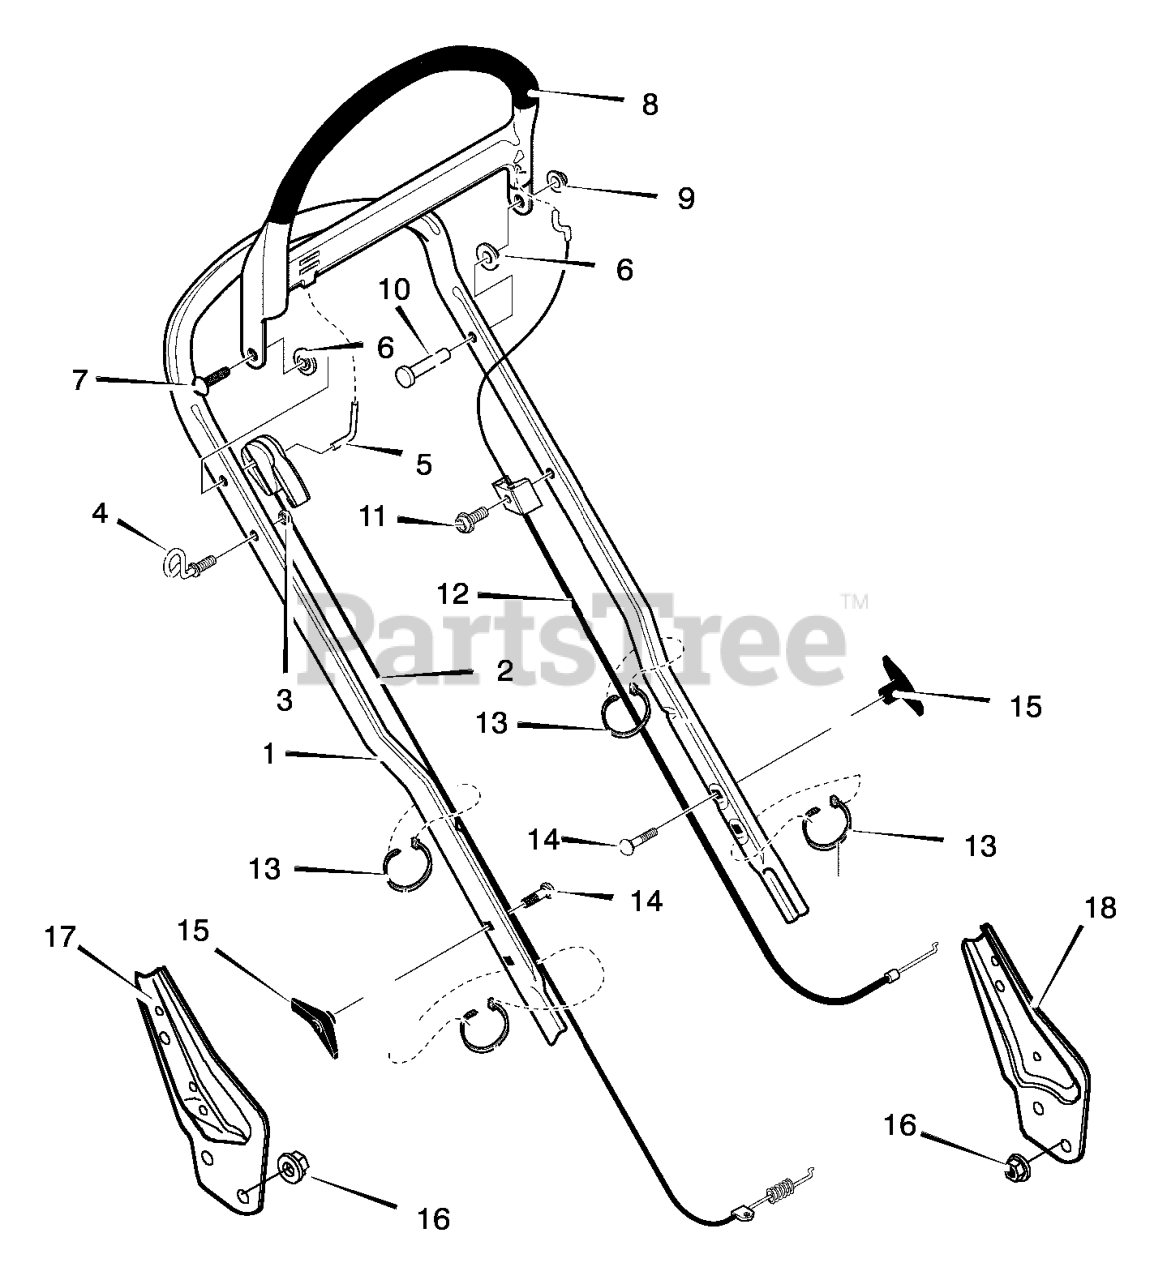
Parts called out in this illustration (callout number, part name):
1	Handle, Upper (Black)
2	Control, Drive
3	Locknut
4	Guide, Rope
5	Rod, Drive Link
8	Lever, Stop
9	Push- On Cap
10	Pin, Clevis
12	Cable, Stop
13	Strap, Tie
14	Bolt, Carriage
15	Wingnut
16	Nut
17	Bracket, Right Handle
18	Bracket, Left Handle
